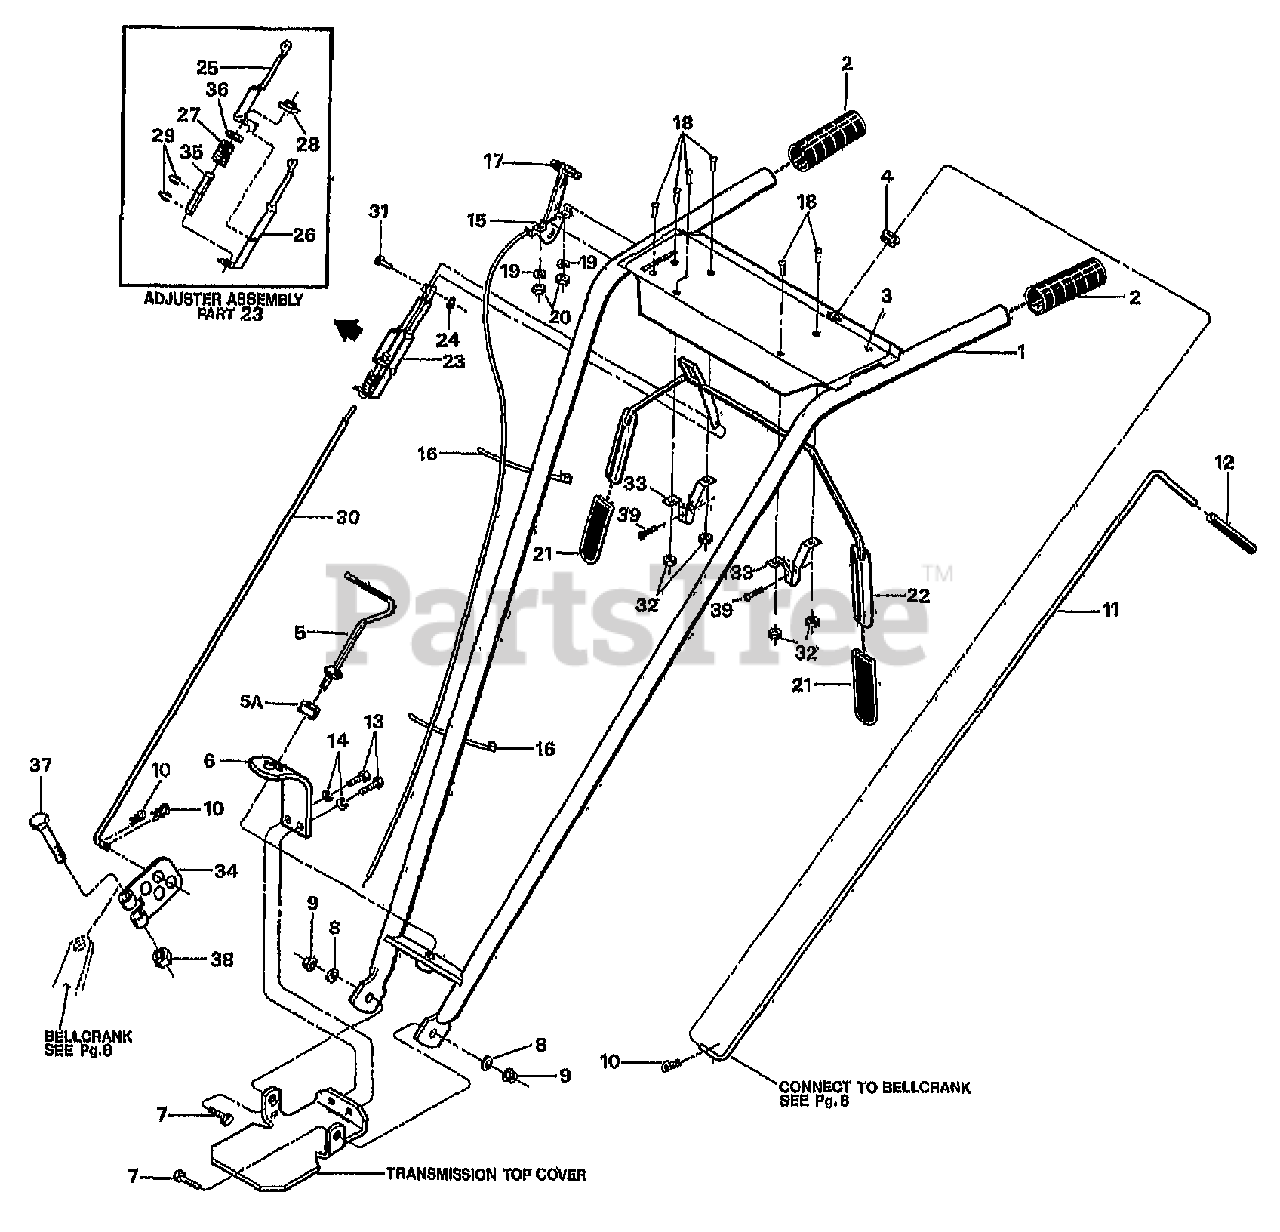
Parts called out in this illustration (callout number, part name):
1	ASSM-HANDLEBAR W/GRIPS (INCL. 2-5A)
2	GRIP-H/B 1" PONY/P-J OPC
3	DECAL-CONTROL PANEL OPC
4	BUSHING-NYLON (PART OF OPER. CONTROL PANEL)
5	ASSM-STUD H/B
5A	WASHER-1.0X.38X.375
6	PLATE-HANDLEBAR ADJUST
7	SCR-HH 3/8-16X1.0 G5 ZP (HANDLEBAR ATTACH.)
8	WASHER-FLAT 3/8 SAE (HANDLEBAR ATTACH.)
9	NUT-LOCK 3/8-16 NYLON ZP (HANDLEBAR ATTACH.)
10	PIN-CLIP (CONN #11 & FRWD CLTCH TO SHFT MECH)
11	ROD-REV W/GRIP OPC (INCL. GRIP #9198)
12	GRIP-CONTROL ROD
13	SCR-HH 3/8-16X.75 (HANDLEBAR ATTACH.)
14	WASHER-LK .375 (HANDLEBAR ATTACH.)
15	CABLE-THROTTLE JR OPC
16	TIE-RED (ATTACH. THROTTLE CABLE TO HANDLEBAR)
17	KNOB-THROTTLE CABLE
18	SCR-RH M10-32X.5 MACH
19	WASHER-LK M10
20	NUT-HH M10-32X.125
21	GRIP-PADDLE SM FRAME OPC
22	BAIL, OPC (W/ 2 #9390 GRIPS)
23	ASSM-ADJUSTMENT OPC (INCL. #25-27, 29 & 36)
24	RING-KLIP .188 DIA
25	ADJUSTER-RT SIDE OPC
26	ADJUSTER-LT SIDE OPC
27	SPRING-ADJUSTER OPC
28	WELDNUT 5/16-18
29	RING-KLIP .500 ZINC
30	ROD-CONTROL OPC
31	ASSM-PIN & CLIP (SMALL FRAME)
32	NUT W/LKWASHER #10-32 ZP
33	BRACKET-BAIL OPC
35	BUSHING-.5X.334X2.88
36	WASHER-.75X.51X.06 ZP
37	SCR-HH 1/4-20X1.5 G5ZP
38	NUT-LK 1/4-20
39	SCR-HWH 1/4-20 X .5 STH
